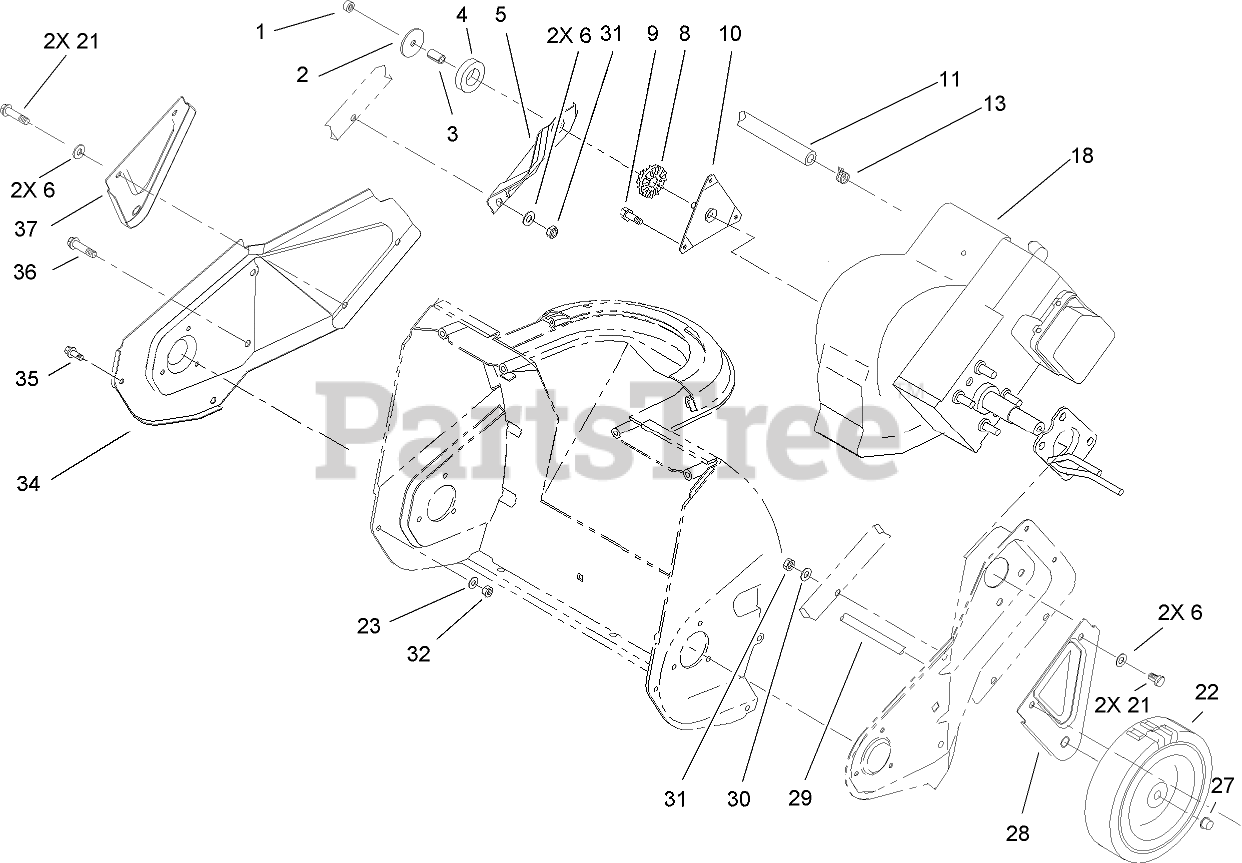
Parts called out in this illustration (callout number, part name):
1	NUT-LOCK, NI
2	WASHER-FLAT
3	SPACER-TUBULAR
4	RING-ISOLATOR
5	BRACKET-SUPPORT, ENGINE
6	WASHER-FLAT
8	BUSHING-ISOLATOR
9	SCREW
10	BRACKET AND STUD ASM
11	HOSE-FUEL
13	CLAMP-HOSE
21	SCREW-HH
22	WHEEL
23	WASHER-FLAT
27	RETAINER-PUSH ON
28	BRACKET-WHEEL, LH
30	WASHER
31	NUT-LOCK, NI
32	NUT-LOCK, NI
34	PLATE-SIDE, RH
36	SCREW-PLASTIC
37	BRACKET-WHEEL, RH
